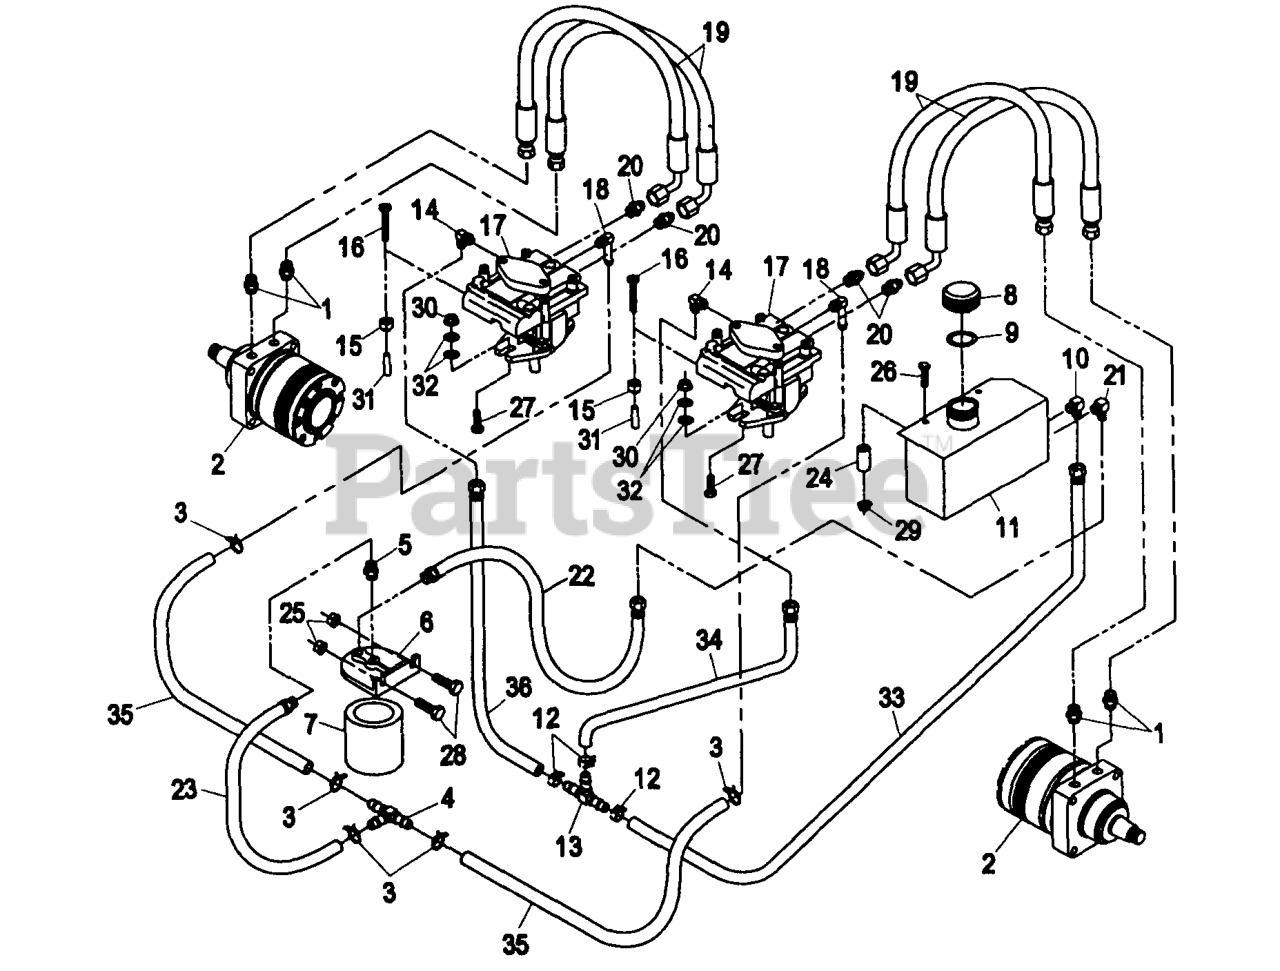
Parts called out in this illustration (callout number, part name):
1	FITTING-STRAIGHT
2	HYD MOTOR ASM
3	CLAMP-HOSE
4	FITTING-TEE, HOSE
5	FITTING-STRAIGHT
9	GASKET-CAP, TANK
10	FITTING-ELBOW
12	CLAMP-HOSE
13	FITTING-TEE, HOSE
14	FITTING-90 DEG
18	FITTING
19	HOSE-PRESSURE, HIGH
20	FITTING-STRAIGHT
21	FITTING-ELBOW
22	ASM,HOSE LO PRESSURE
23	ASM,HOSE CHARGE LINE
31	GRIP-VALVE, DUMP
33	ASM,HOSE CASE DRAIN
34	HOSE ASM
36	HOSE ASM
